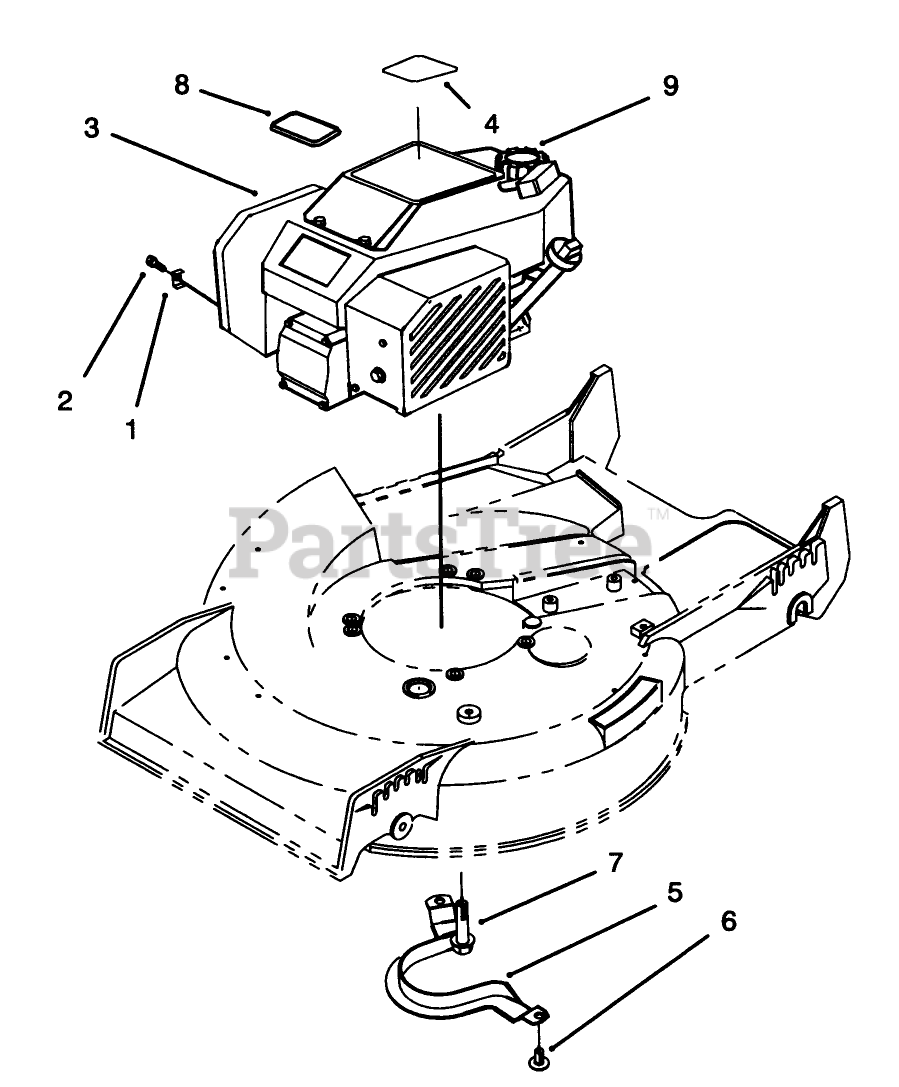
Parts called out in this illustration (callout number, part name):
1	CLAMP-CASING
2	Screw
3	Engine (Incl. Ref. #4 & 8)
4	DECAL - ENGINE
5	Guide-Belt
6	SCREW-HWH
7	SCREW-HWH
8	PLATE-LOGO
9	GAS CAP ASM
